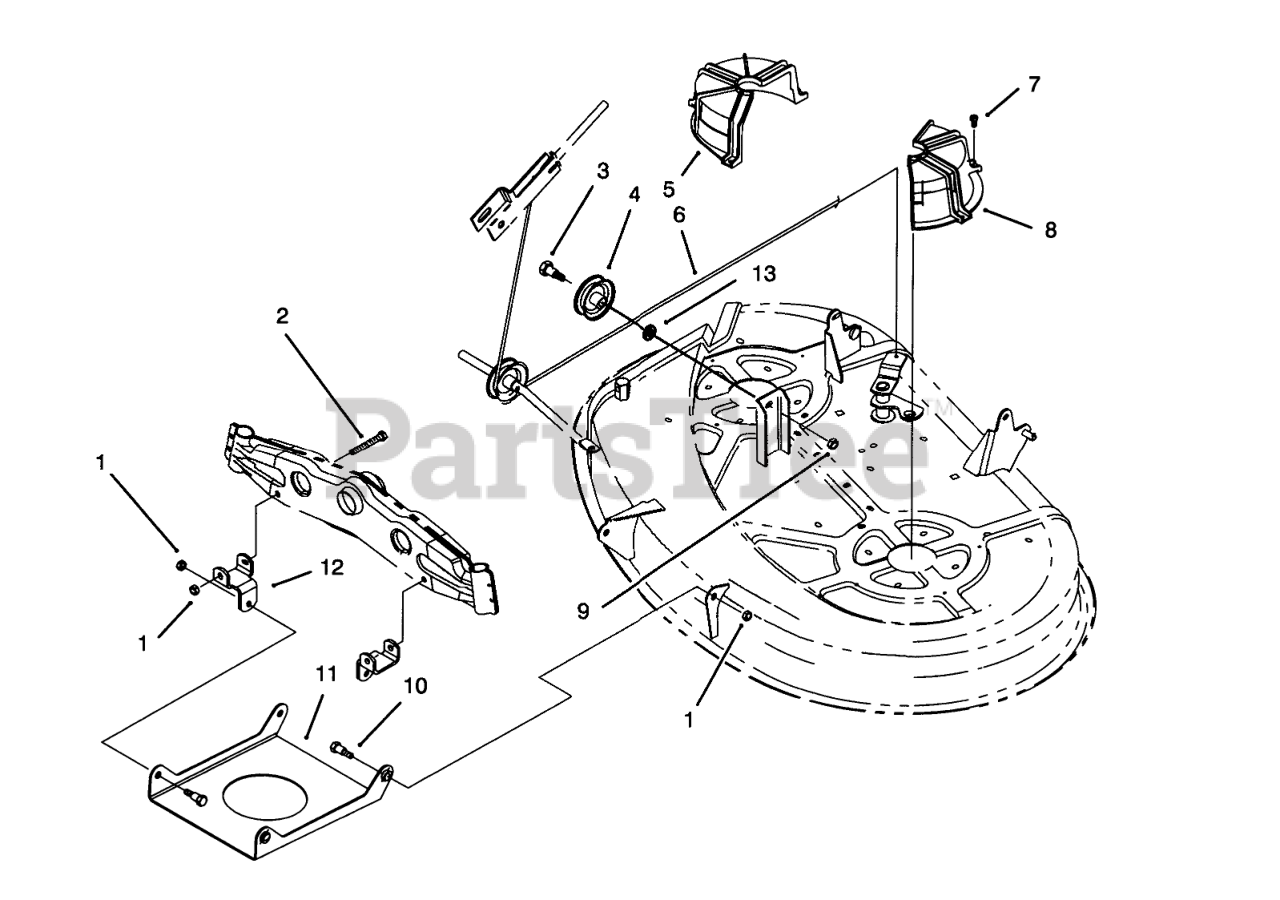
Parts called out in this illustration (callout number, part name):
1	NUT-LOCK, NI
2	SCREW-HH
3	SCREW-SHOULDER, HH
4	PULLEY, CABLE
5	GUIDE-BELT, RH
6	DECK ENGAGE CABLE
7	SCREW-HWHTF
8	GUIDE-BELT, LH
9	NUT-LOCK, NI
10	BOLT-SHOULDER
11	Pan-Front Deck Suspension
12	Bracket-Deck Suspension
13	WASHER-FLAT
